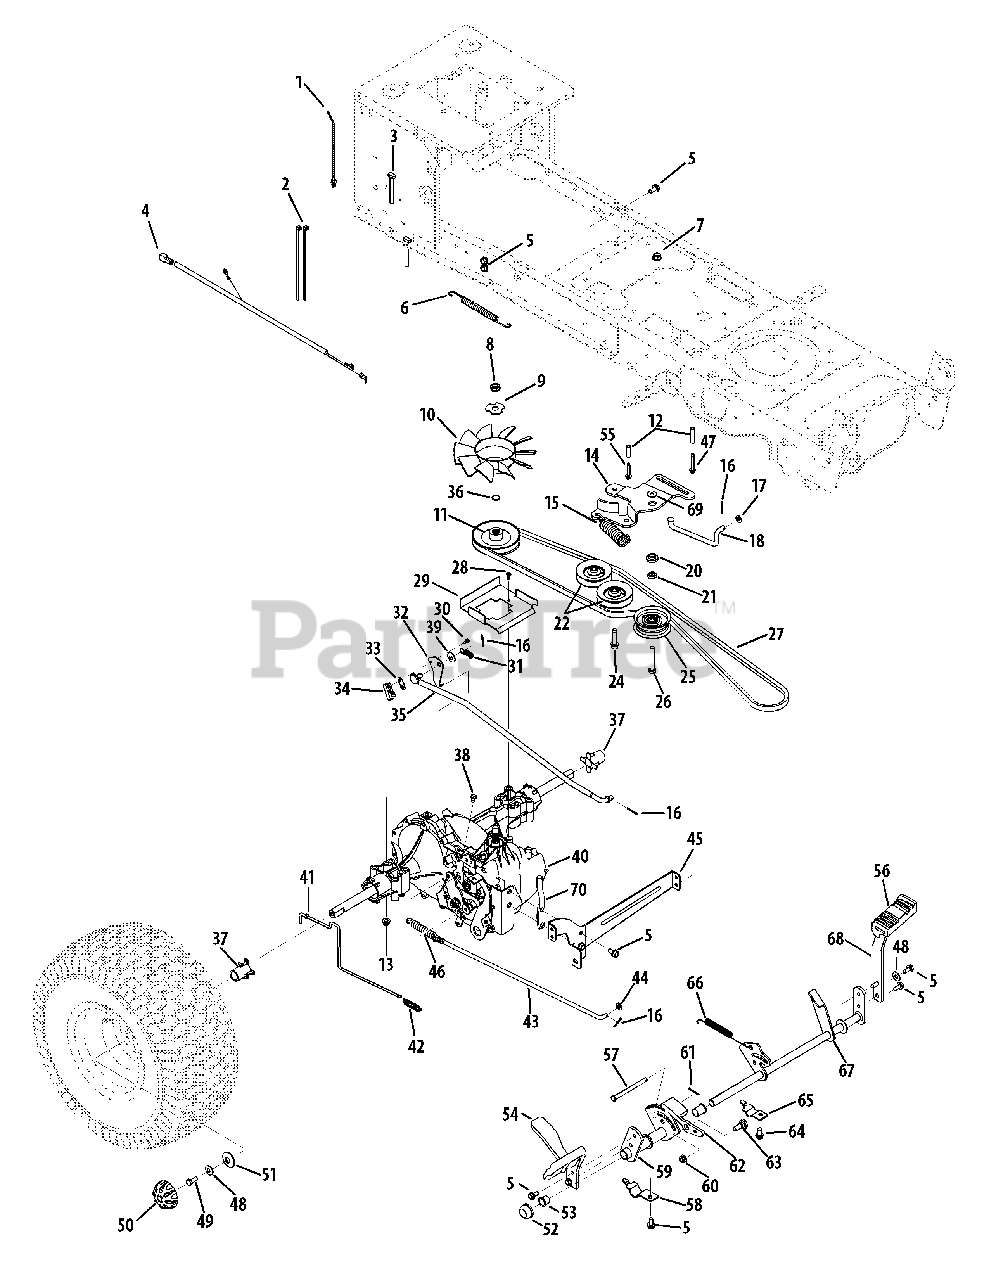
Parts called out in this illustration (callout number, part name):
1	Cable Tie, 7.5
2	Cable Tie, 3/16 x .05 x 7.4
3	Hex Bolt 5/16-18 x 2.75
4	Jumper Harness
5	S-Tapp Scr 5/16-18 x .75
6	Extension Spring .50 dia. x 12.6
7	Flange Locknut 3/8-16 Gr. F
8	Jam Locknut 1/2-10
12	Spacer, .260 x .372 x 1.420
13	Flange Locknut 5/16-18 Gr. F, Nylon
14	Idler Bracket
15	Extension Spring .59 x 4.0
16	Cotter Pin 3/32 dia x 1.00 Lg.
17	Flat Washer .330 x .630 x .0635
18	Pedal Transmission By pass Rod
20	Shoulder Spacer 1.375 x .38 x .183
21	Hex Jam Nut 7/16-20
24	Hex L-Wash HD Scr 3/8-16 x 1.5
25	Idler Pulley, Flat 2.75 OD
26	Hex Bolt 3/8-16 x 2.25" Lg.
28	Truss Mach B-Tapp Scr #10 X .50
30	Hex Washer Screw #8-18 x .50
31	Extension Spring 3/8 x 1.44
32	Switch Actuator Bracket
33	Insulator Nut Plate
34	Short Spring Switch
35	Hydro Control Rod
37	Sleeve 0.765 x 1.5
38	Hex Wash HD Tapp Scr 1/4-20 x .375
39	Flat Washer .406 ID x .812 OD x .134
40	Hydro Transmission
41	Hydro By pass Rod
42	Extension Spring .47 OD x 2.03 Lg.
44	Flat Washer .312 ID x .75 OD
46	Extension Spring .59 x 4.0
47	Hex Washer Hd. TT Screw 1/4-20 x 1.75
48	Cupped Washer .345 ID x .88 OD x .060
49	Hex L-Bolt 5/16-24 x .75 Gr. 5
50	Hub Cap
51	Flat Washer, .350 x 1.59 x .062
52	Push Cap 5/8" Dia Rod
53	Nyliner Flanged Brg.
55	Hex Washer Hd. TT Screw 1/4-20 x 1.625
56	Brake Pedal Pad
57	Clevis Pin 5/16 x 3.985
58	Transmission Rod Support Strap
59	Hydro Pedal Brkt. Assembly
60	Flange Lock-Nut 3/8-16 Gr. F Nylon
61	Bow-Tie Cotter Pin
63	Shoulder Screw .500 x .25
64	Self-tap ping Screw 5/16-18 x .625
65	Brake Shaft Support Strap
66	Extension Spring .63 x 4.95
67	Brake Control Assembly
69	Flat Washer .385 ID x 1.0 x .030
70	Belt Keeper Rod
